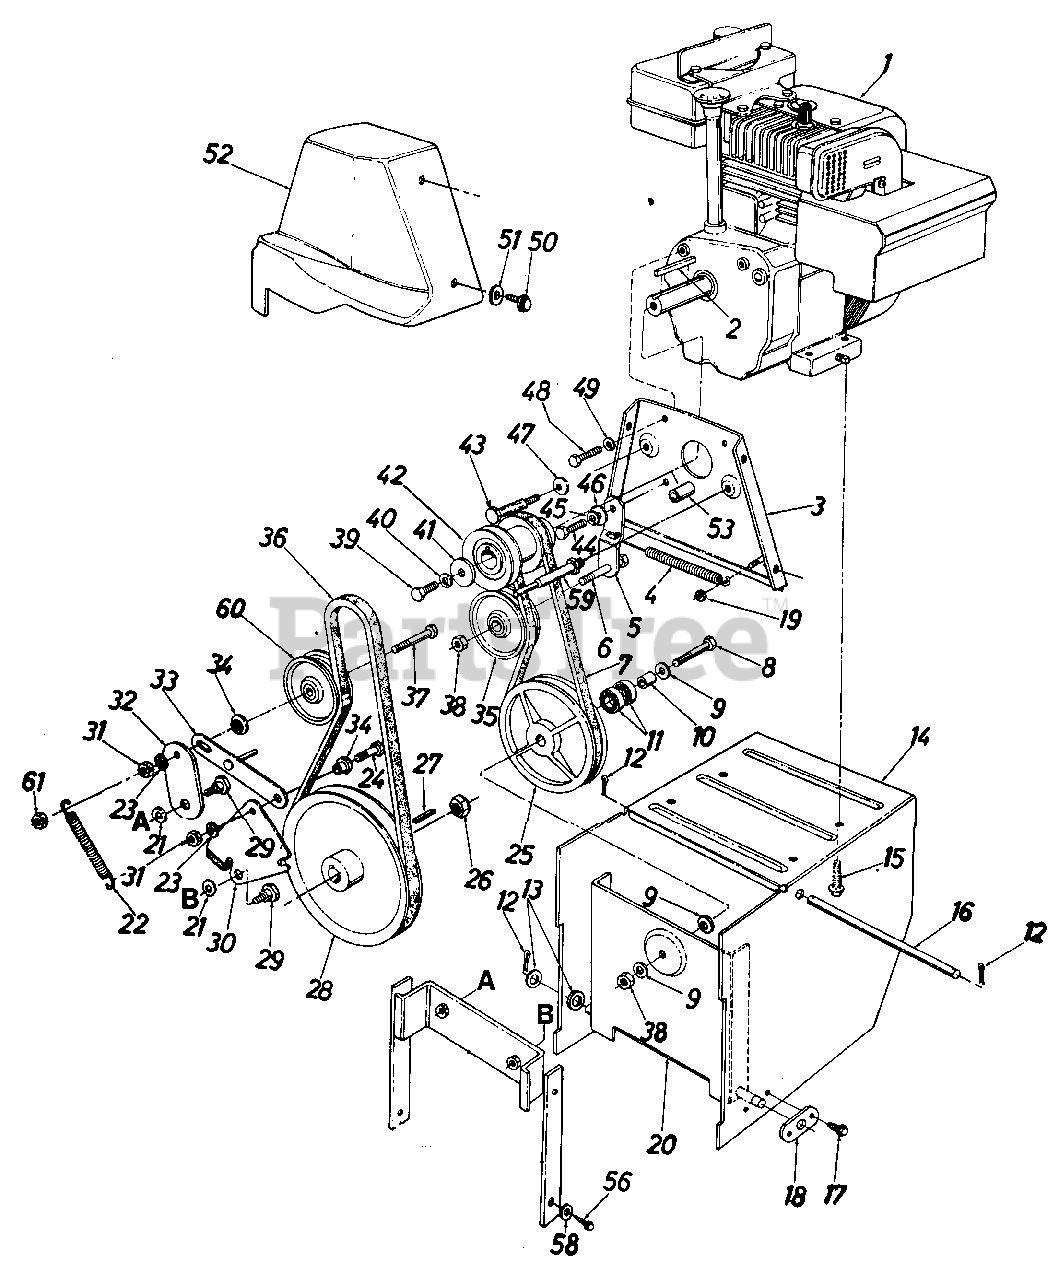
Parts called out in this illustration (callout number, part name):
1	Engine
2	Sq. Key 3116" x 1.5" Lg.
3	Engine Plate Ass'y.
4	Extension Spring .50" O.D. x 3.97" Lg.
5	Drive Clutch Idler Brkt.
6	Hex Bolt 3/8-24 x 1.25" Lg.
7	"V"-Belt
8	Hex Bolt 3/8-24 x 1.50" Lg.
9	Bell-Wash. .40" I.D. x .88" O.D. x .06
10	Spacer .38" I.D. x .62" O.D. x.75" Lg.
11	Ball Brg. .62" I.D. x 1.38" O.D. x .44
12	Cotter Pin 3/32" Dia. x .75"
13	Fl-Wash. .53" I.D. x 1.00" O.D. x .125
14	Frame Ass'y.
15	Hex Wash. Hd. Self-Tap Scr. 3/8-16 x 1.25" Lg.
16	Shaft .50" Dia. x 9.50" Lg.
17	Hex Wash. Hd. Self-Tap Scr. 1/4-20 x .50" Lg.
18	Axle Bracket
19	Hex L-Nut 1/4-20 Thd.
20	Drive Pulley Support Brkt. Ass'y.
21	Bell-Wash. .40" I.D. x 1.13" O.D.
22	Extension Spring .5 O.D. x
23	L-Wash. 3/8" I.D.
24	Hex Bolt 3/8-16 x 1.25" Lg.
25	6.00" O.D. Drive Pulley Ass'y.
26	Hex Jam Cent. L-Nut 5/8-18 Thd.
27	Sq. Key 3/16 x .75" Lg.
28	518" V-Pulley .628" I.D. x 7.50" O.D.
29	Shld. Bolt .625" Dia. x .170" Lg. (3/8-16)
30	Brake Bracket Ass'y.
31	Hex Ins. L-Nut 3/8-16 Thd.
32	Auger Clutch Idler Brkt.
33	Brake Linkage Ass'y.
34	Shld. Spacer.625" I.D.
35	Flat Idler 2.25" O.D.
36	"V"-Belt
37	Hex Bolt 3/8-16 x 2.00" Lg.
38	Hex Ins. Jam L-Nut 3/8-24 Thd.
39	Hex Bolt 3/8-24 x 1.50" Lg.
40	L-Wash. 3/8" I.D.
41	Bell-Wash. .40" I.D. x 1.25" O.D.
42	Double Groove Engine Pulley
43	Shld. Scr. .498" x 3.0" Lg.
44	Hex Bolt 5/16-24 x 1.0" Lg.
45	L-Wash. 5/16" I.D.
46	Shld. Spacer .320" I.D.
47	Bell-Wash. .40" I.D. x .88"
48	Hex Bolt 5/16-24 x .62" Lg.
49	L-Wash. 5/16" I.D.
50	Hex Wash. Hd. Self-Tap Scr. 1/4-20 x .50" Lg.
51	Fl-Wash. .28" I.D. x .75" O.D. x .06
52	Belt Cover
53	Spacer
56	Hex Wash. Hd. Self-Tap Scr. 3/8-16 x .75" Lg.
58	L-Wash. 3/8" I.D. H.D.
59	Stud 3/8-16 x 3.37" Lg.
60	Flat Idler 3.12" O.D.
61	Hex Cent. L-Nut 3/8-16 Thd.
